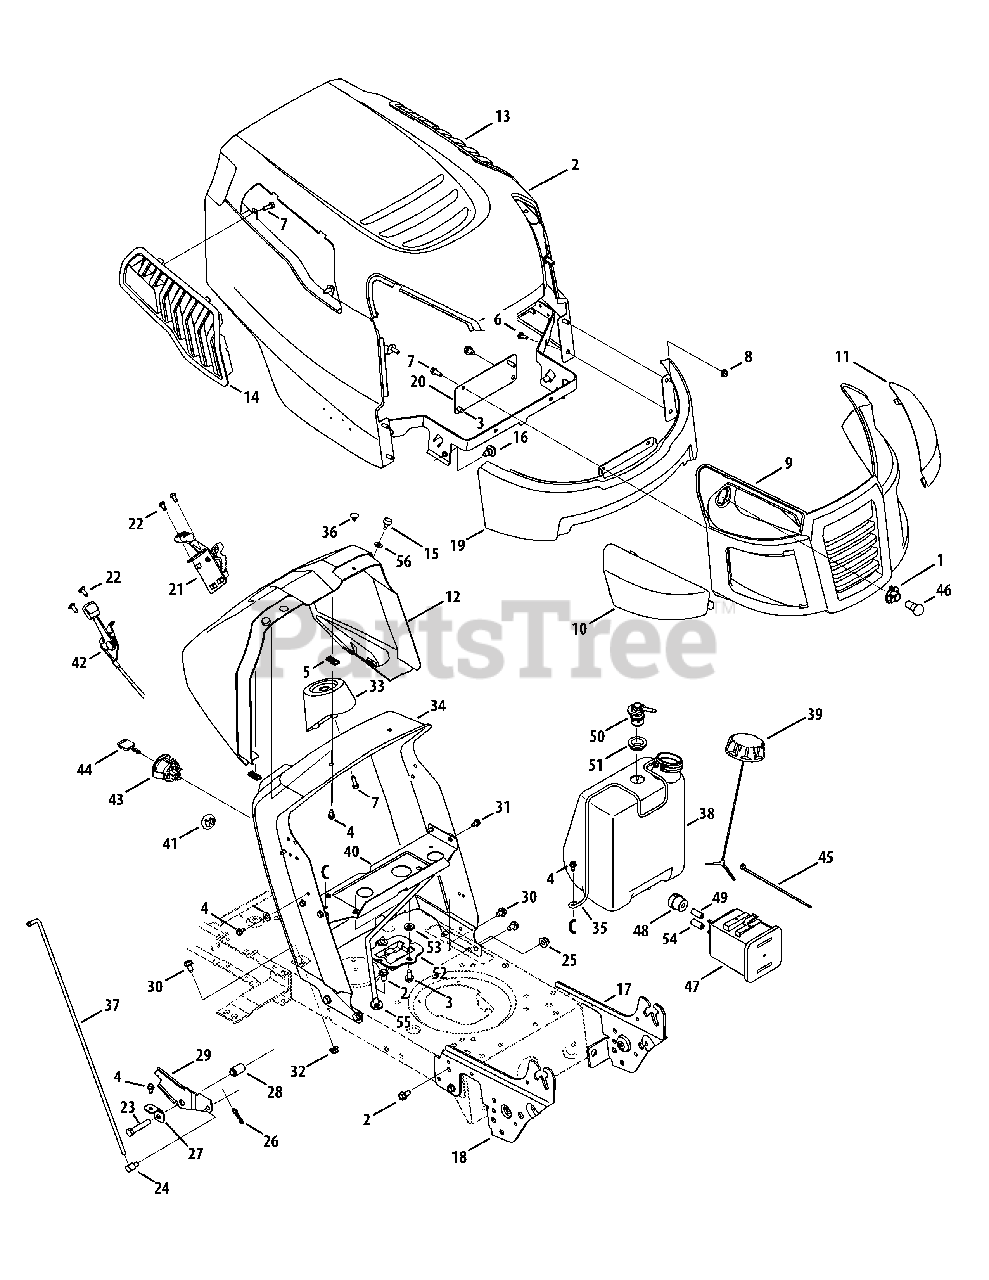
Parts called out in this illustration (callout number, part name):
1	Bulb Socket
2	Hood Assembly
3	Screw, 5/16-18 x .750
4	Hex Washer Screw, 1/4-20 x .500
5	Tin Clip Nut, 1/4-20
6	Hex Screw, 1/4-20 x .620
7	Screw, 1/4 x .750
8	Nut, Hex Flange Insert Lock, 1/4-20
9	Grill
10	Headlight Lens, RH
11	Headlight Lens, LH
12	Dash Collar
13	Hood Scoop, LH
14	Hood Scoop, RH
15	Bumper
16	Shoulder Screw, 5/16-18
17	Left Support Pivot Bracket
18	Right Support Pivot Bracket
19	Lower Grill
20	Lower Grill Bracket
21	Parking Brake Lever Assembly
22	Self-Tap Screw, 1/4-20
23	Hex Head Screw, 3/8-16
24	Ferrule, 1/4-20 x 1.00
25	Nut, Hex Flange Insert Lock, 3/8-16
26	Cotter Pin
27	Speed Latch Tab
28	Flange Spacer
29	Speed latch
30	Self-Tap Screw, 1/4-20
31	Hex Screw, 1/4-15
32	Nut, Hex Flange Lock, 5/16-18
33	Steering Support
35	Fuel Tank Support Rod
36	Ratchet Clip
37	Speed Selector Control Rod
38	1.38 Gallon Fuel Tank
39	Fuel Cap
40	Gas Tank Support Bracket
41	Choke Plug
42	Throttle/Choke Assembly
43	3-position Key Switch
44	Key (2 pack)
45	Cable Tie
46	Headlight Bulb
47	Carbon Canister
48	Filter Vent
49	Low Perm Fuel Line 3/16 White
50	Rollover Valve
51	Rubber Grommet
52	Canister Bracket
53	Flat Washer, .344 x.750 x .120
54	Low Perm Fuel Line 7/32 Yellow
55	Dash Support Rod
56	Flat Washer, .250 x .630 x .052
